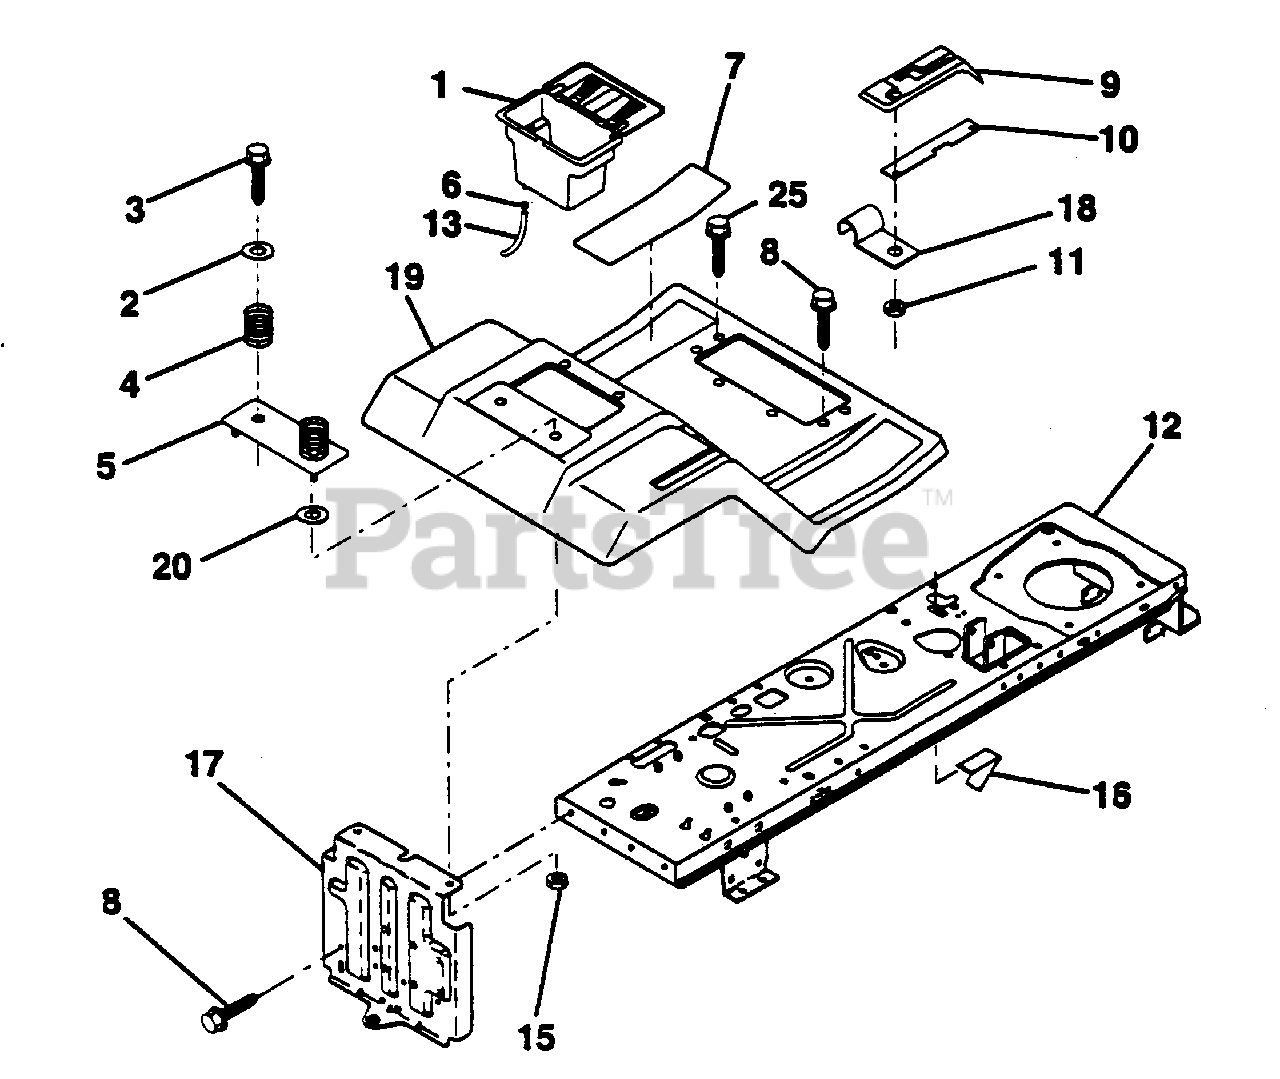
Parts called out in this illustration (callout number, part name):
1	Case, Battery (AYP part number)
2	Washer 13/32 x 1-1/4 x 12 Ga. (AYP part number)
3	Screw, Hex Wsh. Thrdrol. 3/8-16 x 3/4 (AYP part number)
4	Spring, Compression, Seat (AYP part number)
5	Plate, Asm. Battery (AYP part number)
6	Clamp, Hose (AYP part number)
7	Pad, Footrest (AYP part number)
8	Screw, Hex Wsh Thdrol. 5/16-18 x 3/4
9	Console, Shift Control (AYP part number)
10	Bar, Shift Lock (AYP part number)
11	Nut, Self-Thrd., Wsh. Head 3/16 (AYP part number)
12	Chassis Asm. Weldment
13	Tube, Battery Drain (AYP part number)
15	Nut, Keps Hex 1/4-20 UNC (AYP part number)
16	Switch Actuator (AYP part number)
17	Drawbar (AYP part number)
18	Clip, Insulated (AYP part number)
19	Fender/Footrest (AYP part number)
20	Washer 9/32 x 7/8 x 13 Ga. (AYP part number)
25	Screw Hex 5/16-18 x 1 (AYP part number)
